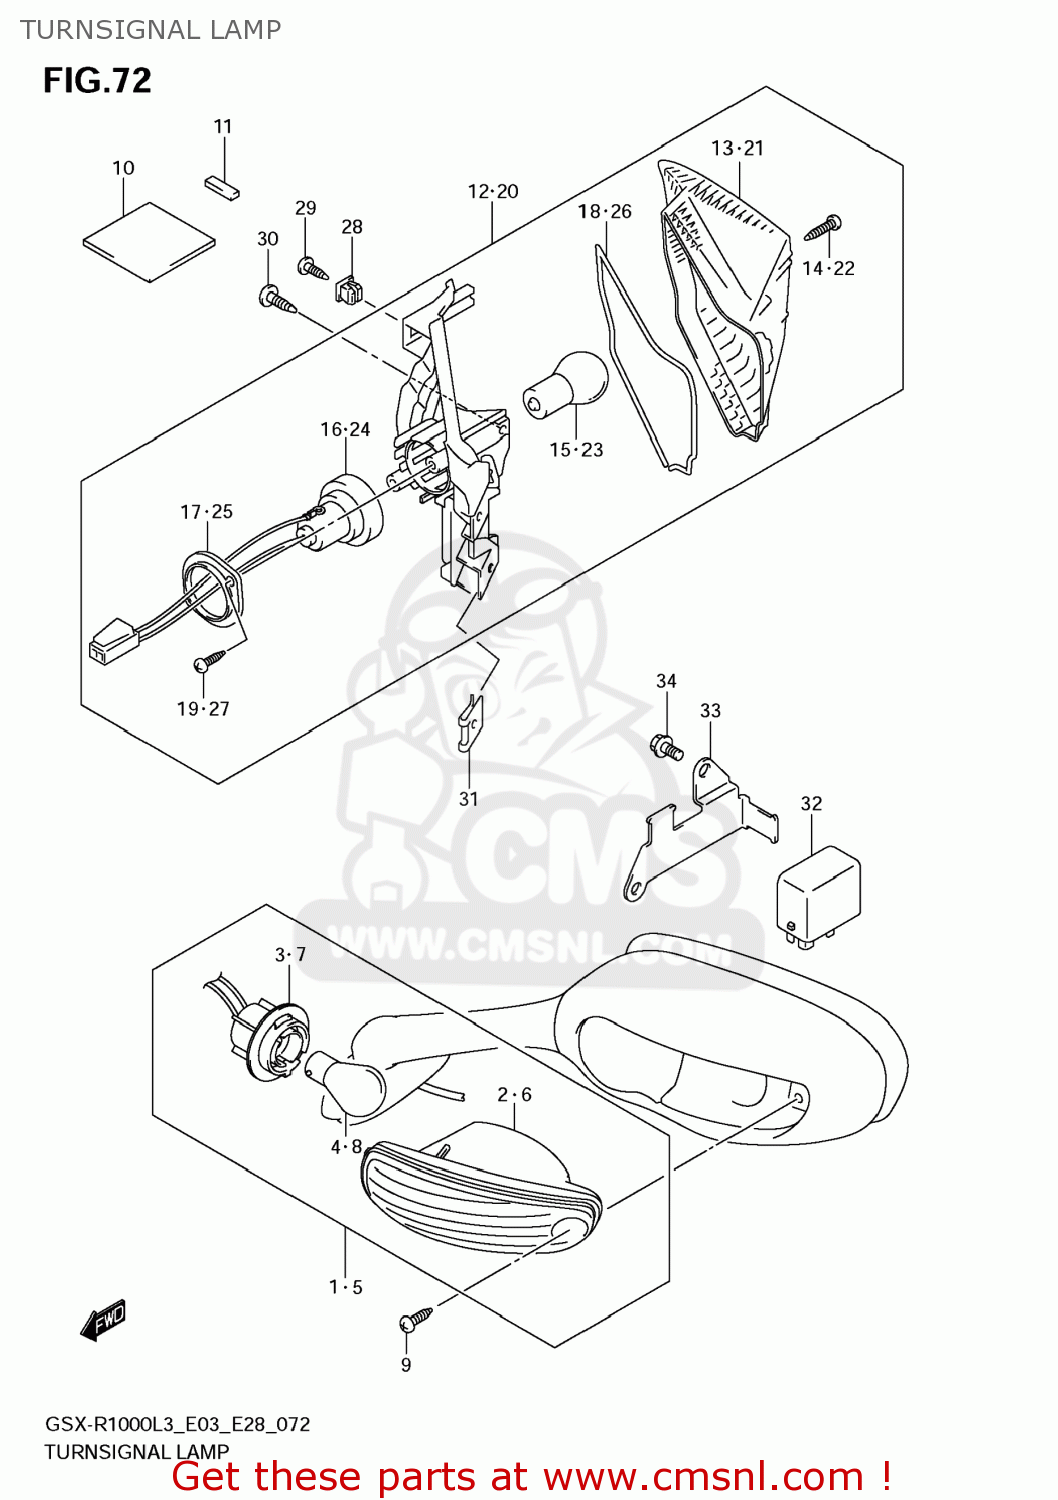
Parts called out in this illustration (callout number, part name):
1	LAMP ASSY,FR TURN SIGNAL,R
2	LAMP UNIT,R
3	SOCKET,R
4	BULB(12V21W,AMBER)
5	LAMP ASSY,FR TURN SIGNAL,L
6	LAMP UNIT,L
7	SOCKET,L
8	BULB(12V21W,AMBER)
9	SCREW(4X20)
10	CUSHION(40X20X5)
11	TAPE,FR TURNSIGNAL
12	LAMP ASSY,RR TURNSIGNAL,R
13	LENS,R
14	SCREW
15	BULB(12V21W,AMBER)
16	SOCKET & CORD,R
17	PLATE,RR COMBINATION
18	GASKET (NAS)
19	SCREW
20	LAMP ASSY,RR TURNSIGNAL,L
21	LENS,L
22	SCREW
23	BULB(12V21W,AMBER)
24	SOCKET & CORD,L
25	PLATE,RR COMBINATION
26	GASKET (NAS)
27	SCREW
28	NUT
29	SCREW
30	SCREW
31	NUT
32	RELAY ASSY,TURNSIGNAL LAMP
33	BRACKET,RELAY
34	BOLT
